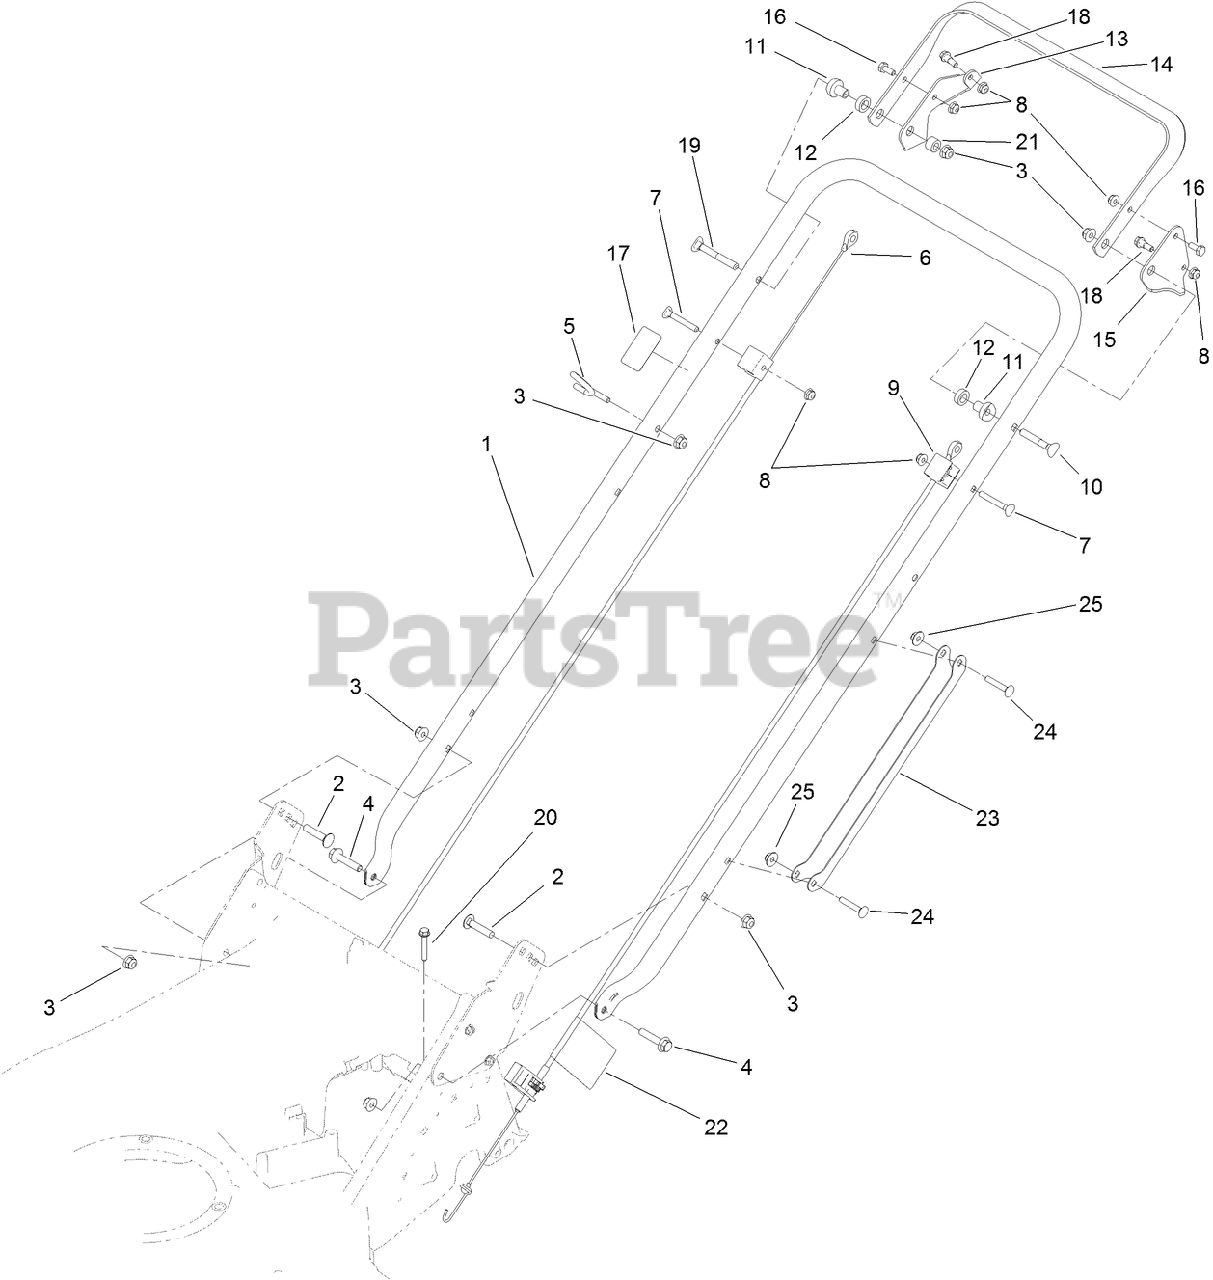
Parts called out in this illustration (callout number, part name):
1	HANDLE
2	BOLT-CARR
3	NUT-HF, NI
4	SCREW-HHF
5	GUIDE,ROPE
6	CABLE-BRAKE
7	SCREW
8	NUT-HF
9	CABLE-TRACTION
10	SCREW-HANDLE
11	SPACER-SUPPORT
12	SPACER-NYLON
13	BRACKET-CONTROL, BRAKE
14	BAR-CONTROL, ZONE START
15	LEVER-CONTROL, TRACTION
16	SCREW-HH
17	DECAL-PRIMER
18	BOLT-SHOULDER
19	SCREW-HANDLE
20	SCREW-HWH
21	SPACER
22	DECAL-ADJUST, SELF PROPEL DRIVE
23	GUARD-CABLE, HANDLE
24	SCREW-CARR
25	NUT-HEX FLG
